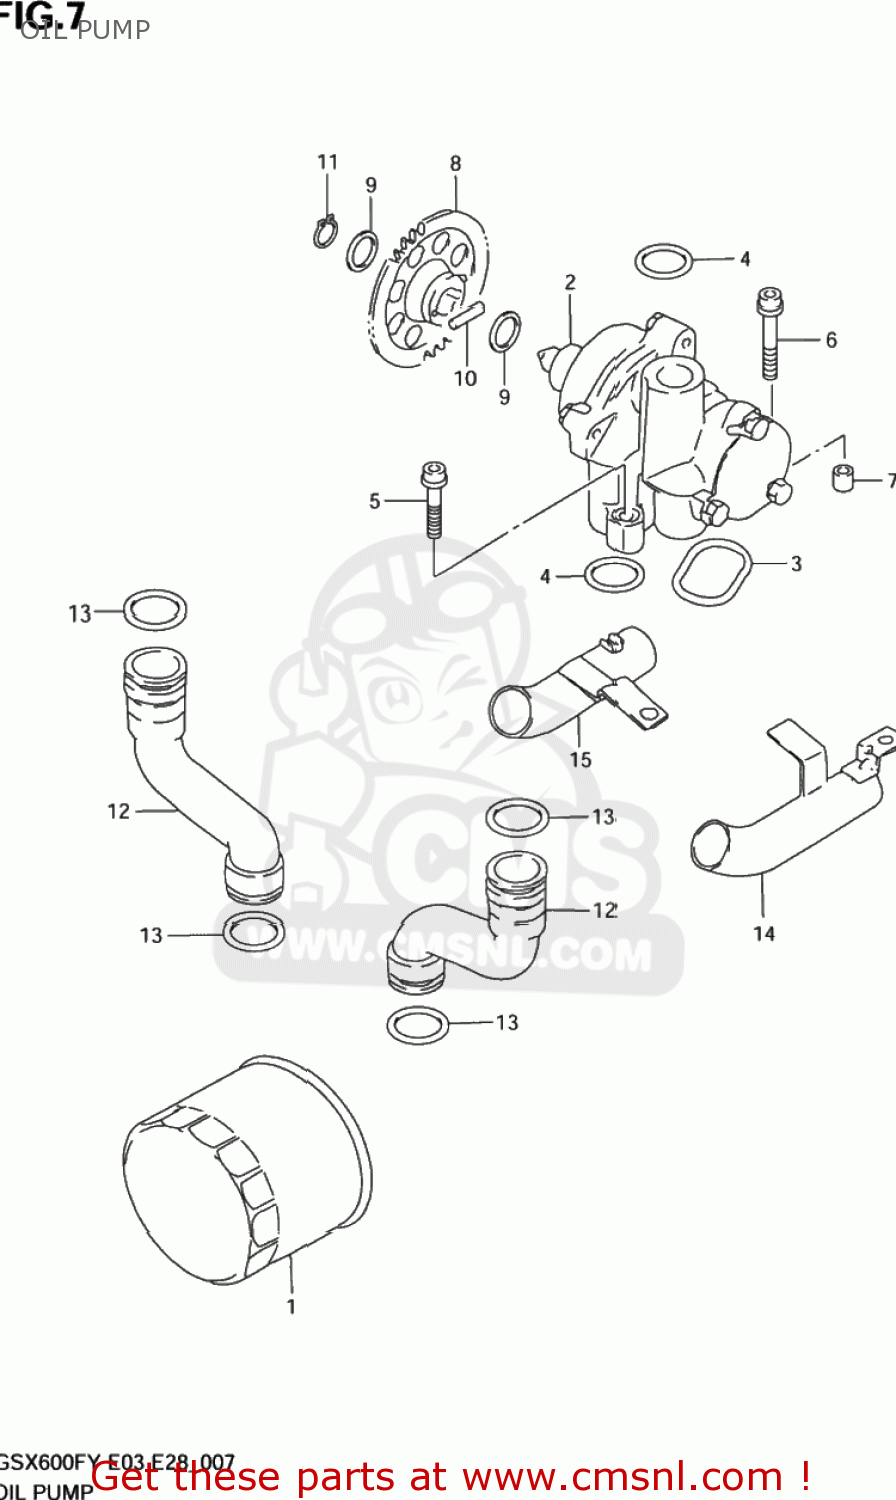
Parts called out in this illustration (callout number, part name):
1	FILTER ASSEMBLY,ENGINE OIL
2	PUMP ASSY,OIL
3	O RING,OIL PUMP
4	O RING(D:3.2,ID:17.8)
5	BOLT
6	BOLT
7	PIN
8	GEAR,OIL PUMP DRIVEN(NT:37)
9	SHIM
10	PIN(5X18)
11	CIRCLIP,12 MM
12	PIPE,OIL OUTLET
13	O RING(D:3.7,ID:21.7)
14	PIPE,OIL OUTLET UNDER,L
15	PIPE,OIL OUTLET UNDER,R
